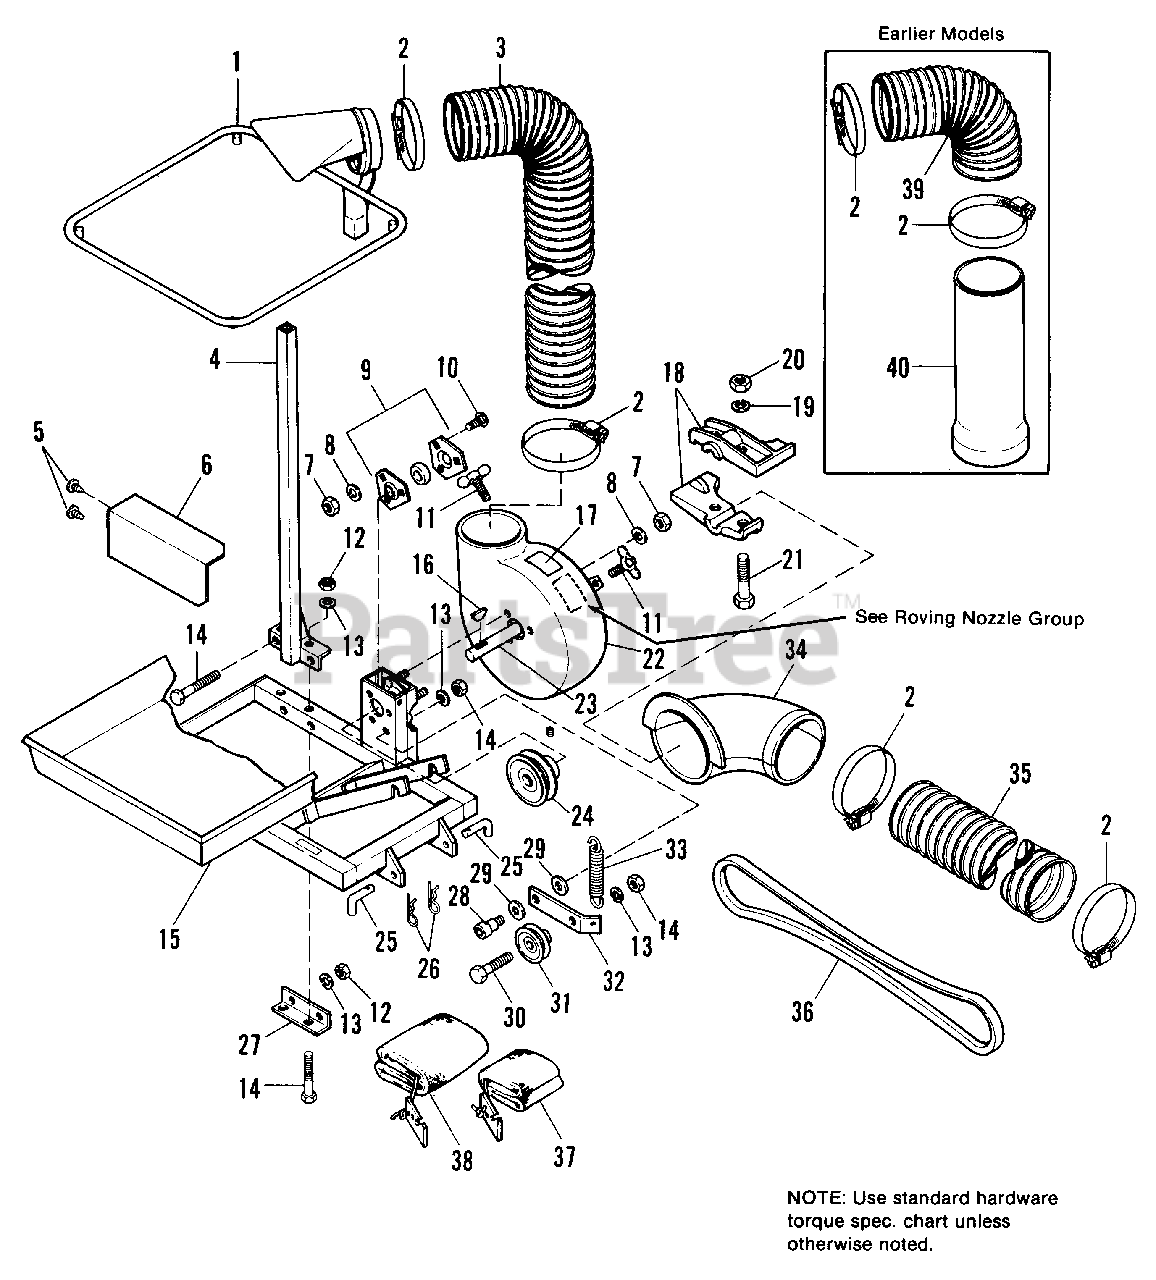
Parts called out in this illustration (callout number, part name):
1	SUPPORTING RING, Bag
2	CLAMP, Hose
3	TUBE, Exhaust
4	UPRIGHT ASSY.
5	SCREW, Self-tapping, #10 x 1/2
6	GUARD, P.T.O. Pulley
7	NUT, Hex, Full, 5/16-18
8	LOCKWASHER, 5/16
9	BEARING & FLANGE ASSY.
10	CARRIAGE BOLT, 5/16-18 x 3/4
11	SCREW, Wing, 5/16-18 x 2
12	NUT, Hex, Full, 3/8-16
13	LOCKWASHER, 3/8
14	CAPSCREW, Hex Hd., 3/8-16 x 2-1/2
15	TRAY ASSY.
16	KEY, Woodruff, #11, 3/16 x 7/8
17	DECAL, Warning
18	BLADES, Blower (Pair)
19	LOCKWASHER, Internal Tooth, 1/2
20	NUT, Hex, Full, 1/2-13
21	CAPSCREW, Hex Hd., 1/2-13 x 1-1/2
22	HOUSING, blower
23	SHAFT, Blower
24	PULLEY, Blower
25	CLEVIS, Mount
26	CLIPS, Hairpin
27	ANGLE, Reinforcement
28	SCREW, Shoulder, Hex Socket Hd., 1/2 x 1/2
29	WASHER, Plain, 1/2
30	CAPSCREW, Hex Hd., 3/8-16 x 2-1/2
31	PULLEY, Idler
32	ARM, Tension (Idler)
33	SPRING, Tension
34	ELBOW, Blower
35	HOSE, Lower, 7" x 45"
36	BELT, Drive
37	TOP, Canvas Bag
38	BAG, Canvas
39	HOSE, Upper (For earlier models)
40	TUBE, Exhaust (For earlier models)
